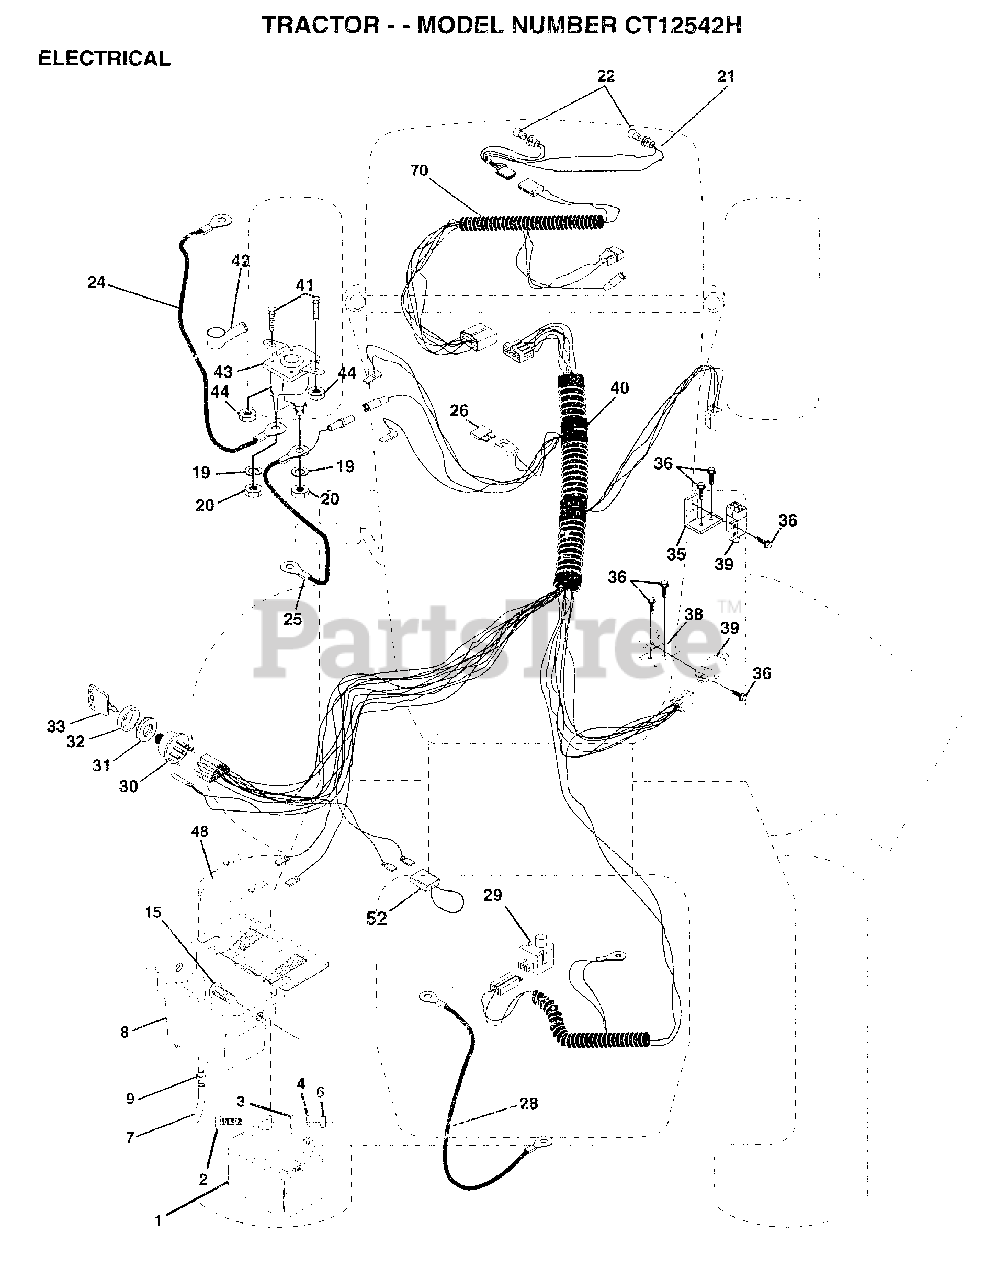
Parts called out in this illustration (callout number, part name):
2	BOLT LT
3	WASHER
4	LOCKWASHER
7	TUBE T
9	HOSE CLAMP T
15	FASTNER.SNAP-IN
20	NUT
21	"HARNESS,LIGHT SOC"
22	HEADLAMP BULB
24	"CABLE T, BATTERY"
25	CABLE.BTRY.6GA.RD
26	FUSE HYT
28	CABLE T
29	SWITCH SEAT
30	SWITCH IGN 4POS
31	NUT IGNITION
32	COVER KEY SWITCH
33	KEY
35	BRACKET LT
36	SCREW
38	BRACKET SWITCH IN
39	SWITCH INTERLOCKT
40	HARNESS.IGNITION
41	BOLT HXHD FIN
44	NUT HXKEP 1/4X20
48	ADAPTER AMMETER
52	PROTECTION LOOP
70	HARNESS.ENGINE
